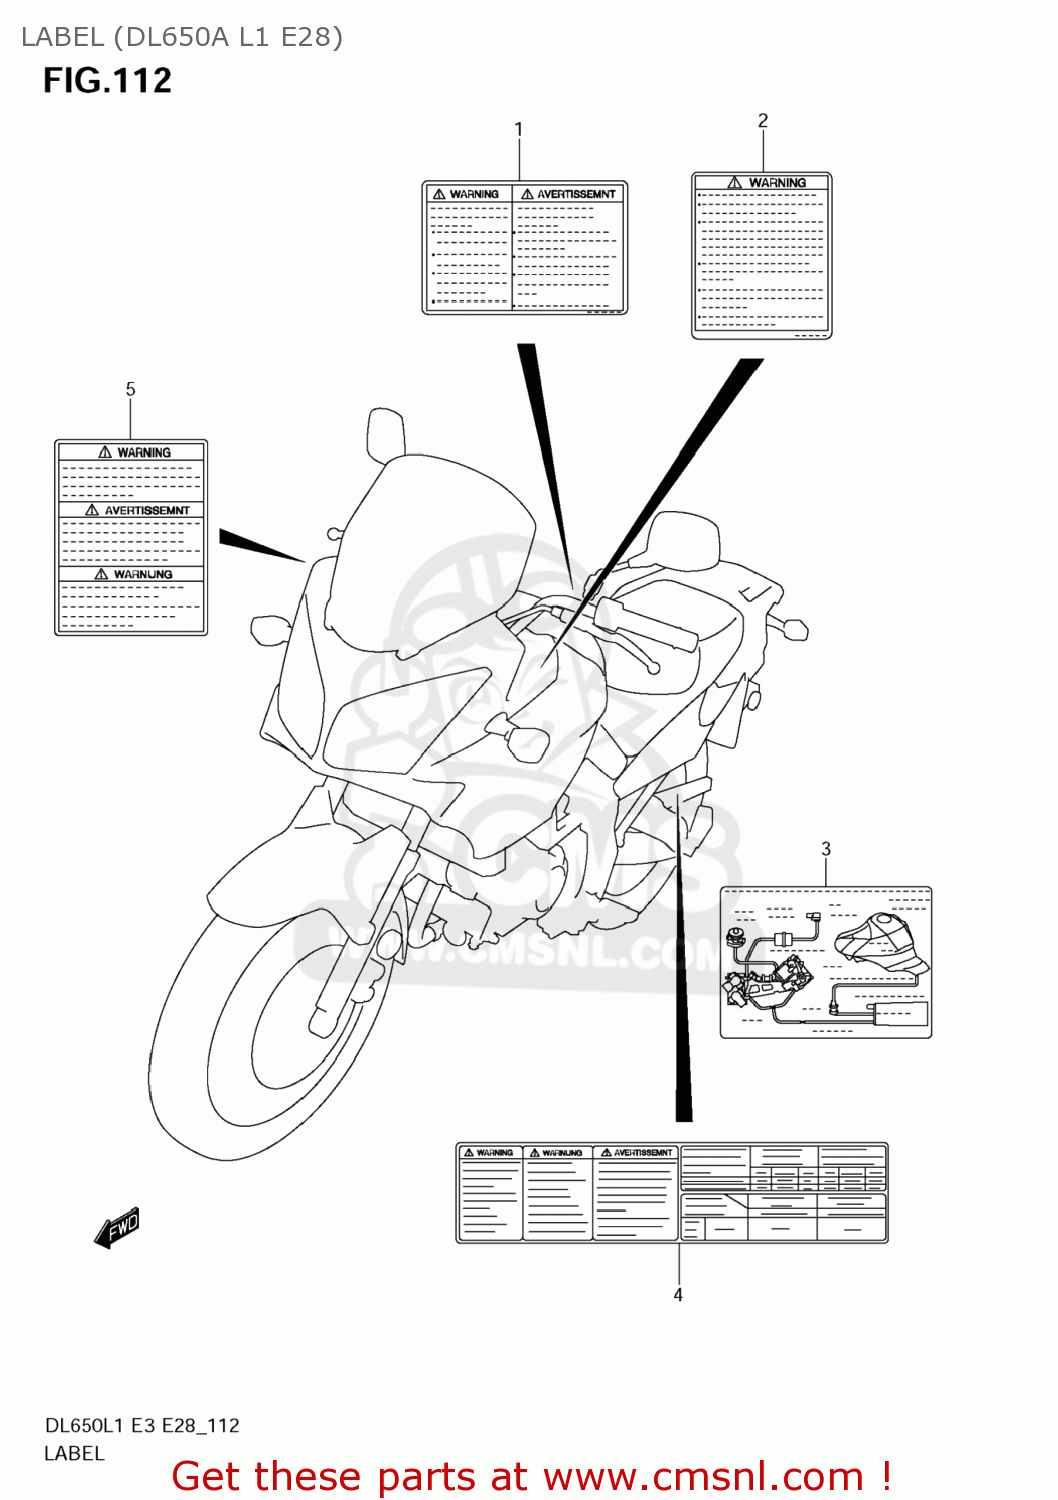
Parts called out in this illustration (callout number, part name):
1	LABEL,GENERAL WARNING
2	LABEL,SCREEN
3	LABEL,TIRE INFORMATION
4	LABEL,WARNING STEERING
5	MANUAL,OWNER'S
